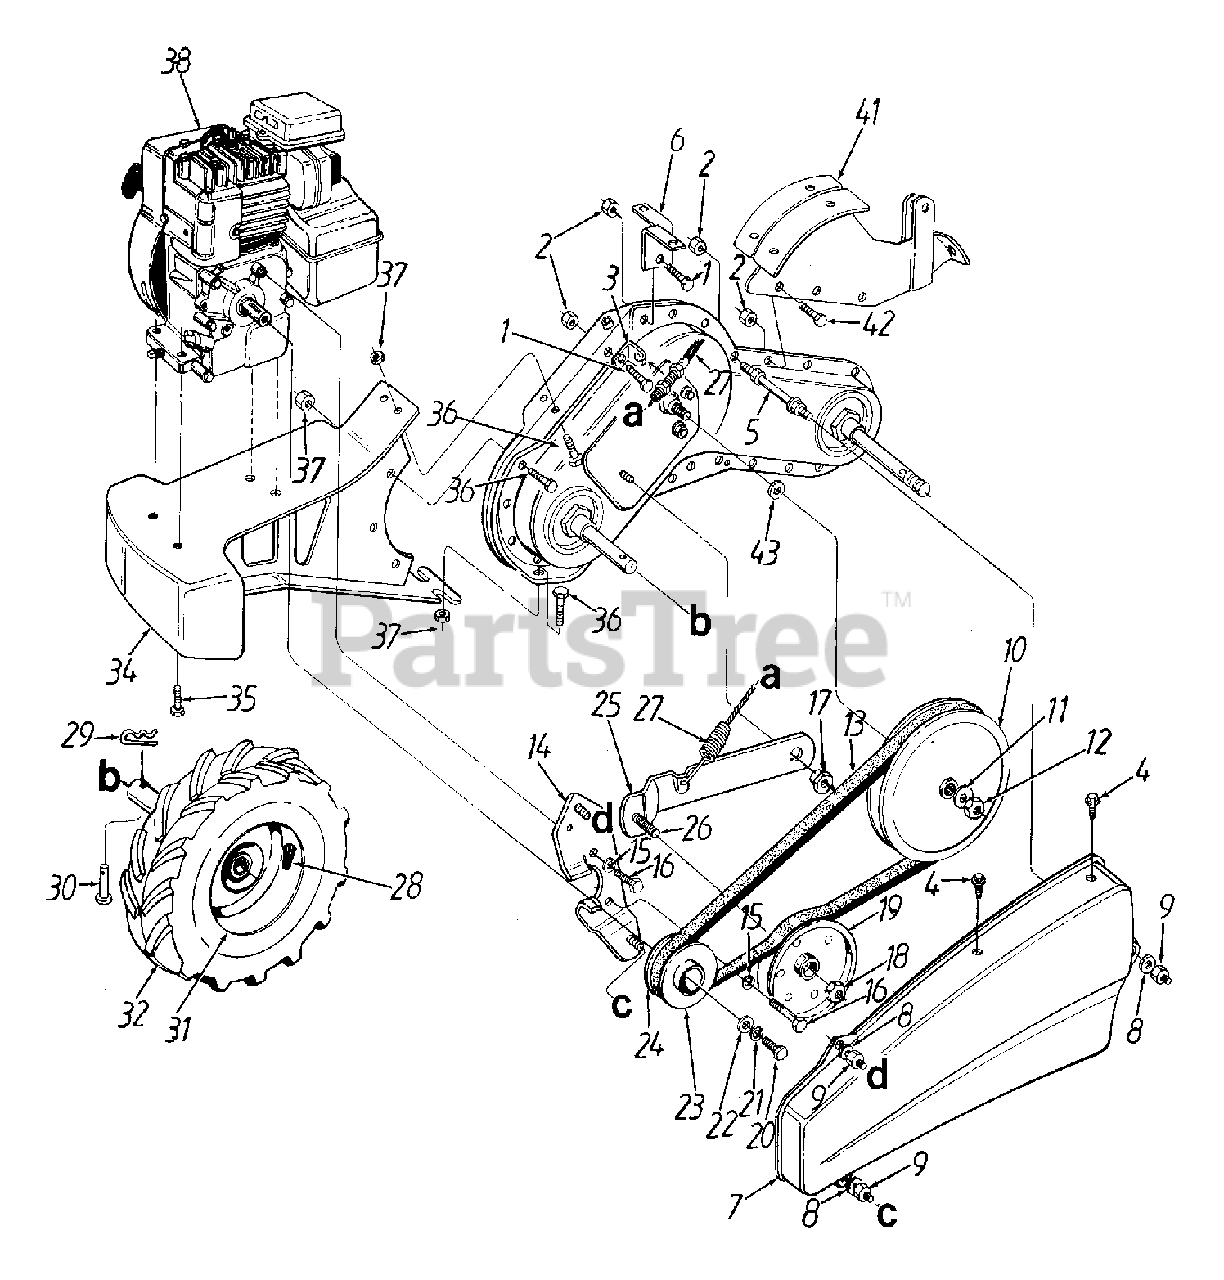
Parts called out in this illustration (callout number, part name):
1	Hex Bolt 5/16-18 x .75"
2	Hex Top L-Nut 5/16-18 Thd.
3	Cable Mtg. Bracket
4	Torx Mach. AB-Tap Scr. 1/4 x .6"
5	Belt Cover Bolt
9	Hex Cap Nut 1/4-28 Thd.
10	Flat Pulley 8" O.D.
11	Bell-Wash. .38" I.D. x .88" O.D.
12	Hex Flange Nut.
13	"V"-Belt
16	Hex Bolt 5/16-24 x .62"
17	Shoulder Nut
18	Hex Jam L-Nut 3/8-16 Thd.
19	Flat Idler w/Flanges
20	Hex Bolt 3/8-24 x 1"
21	Lock Washer 3/8" I.D.
22	Flat Washer 3/8" I.D. x 1" O.D.
23	Outer Engine Pulley Half
24	Inner Engine Pulley Half
26	Hex Bolt 3/8-16 x 1.25"
27	Clutch Cable
28	Air Valve
29	Hairpin Clip
34	Frame Counterweight
35	Hex TT-Tap Scr. 3/8-16 Thd.
36	Hex Bolt 5/16-18 x 1"
37	Hex Flange L-Nut 5/16-18 Thd.
38	Engine
43	Wash. Fl..635 I.D. x .930 O.D. x .03
